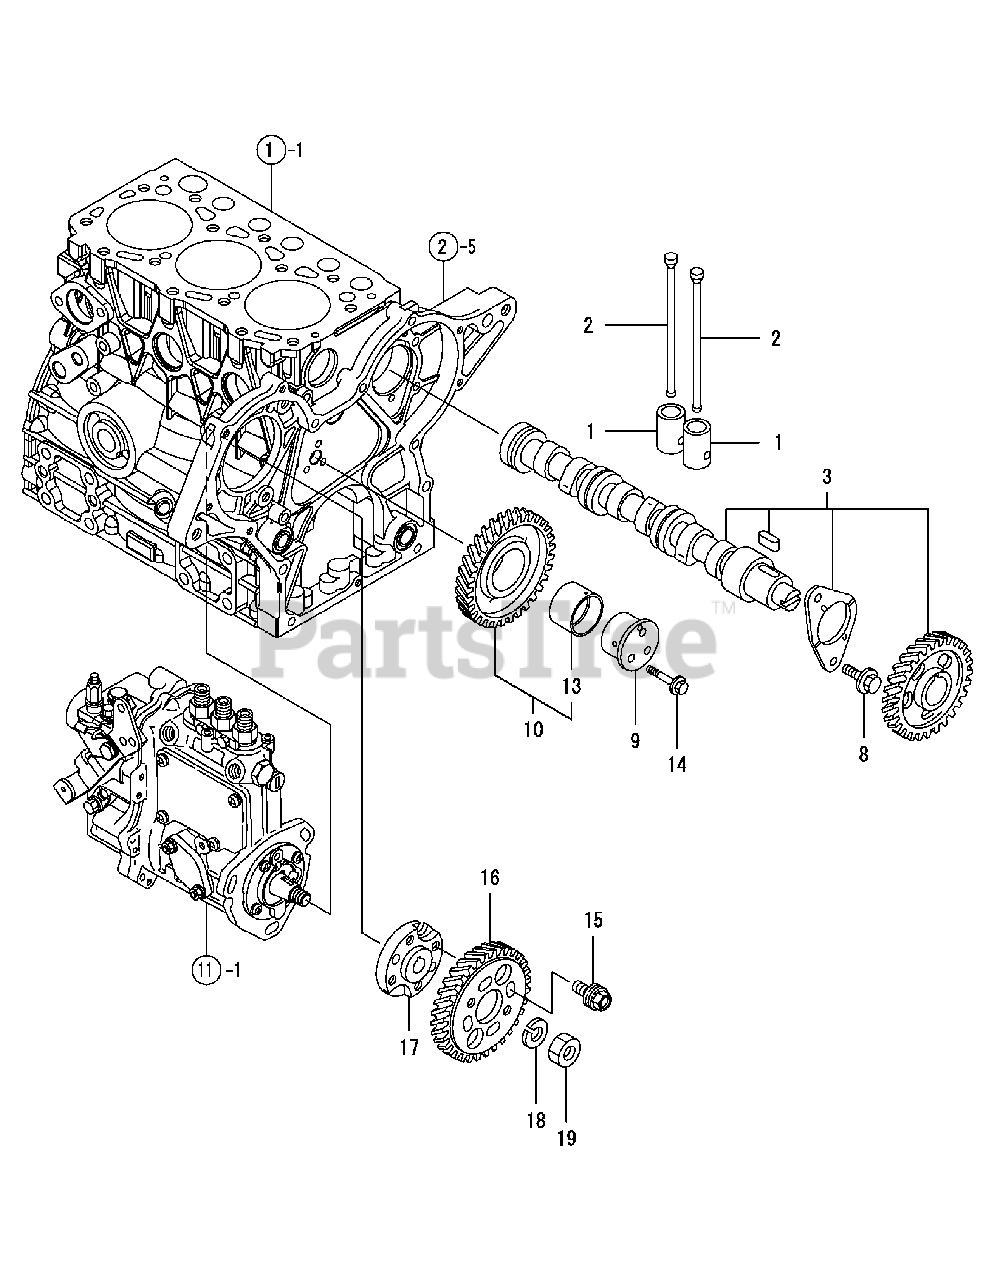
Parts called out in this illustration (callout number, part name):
8	BOLT M 6X 12 PLATED
9	SHAFT, IDLE GEAR
10	GEAR ASSY, IDLE
13	BUSH,IDLE GEAR
14	BOLT M 6X 35 PLATED
18	SPRING WASHER 12
